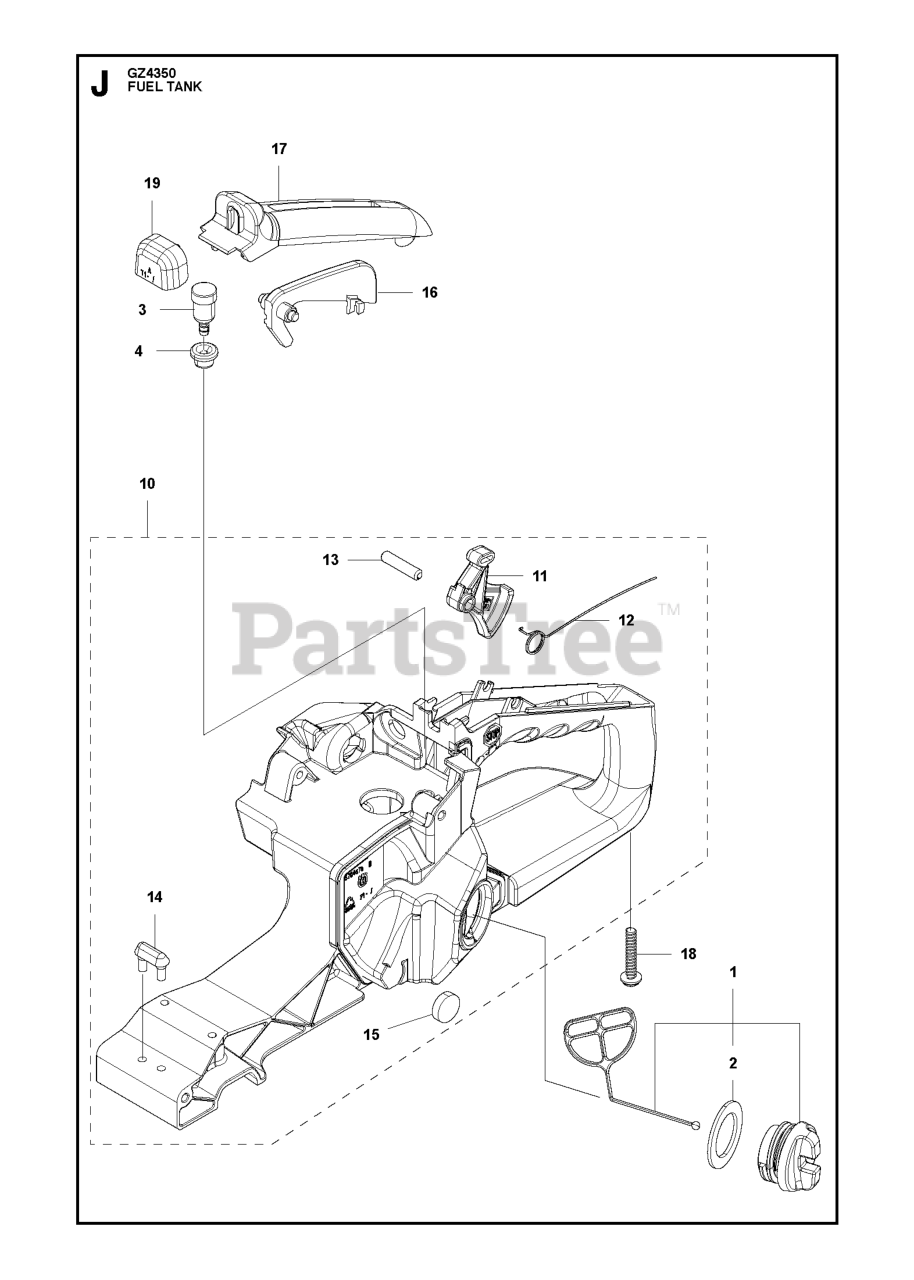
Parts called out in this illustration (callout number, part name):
1	CAP ASSY
3	BREATHER
4	GROMMET
10	HANDLE ASSY (B) STANDARD
11	THROTTLE LEVER
13	SPRING PIN
14	DAMPER(A)
15	HELPER(M) Z285033370
16	ARM (RPLS 335633350-335633352)
17	COVER GRIP BLACK
